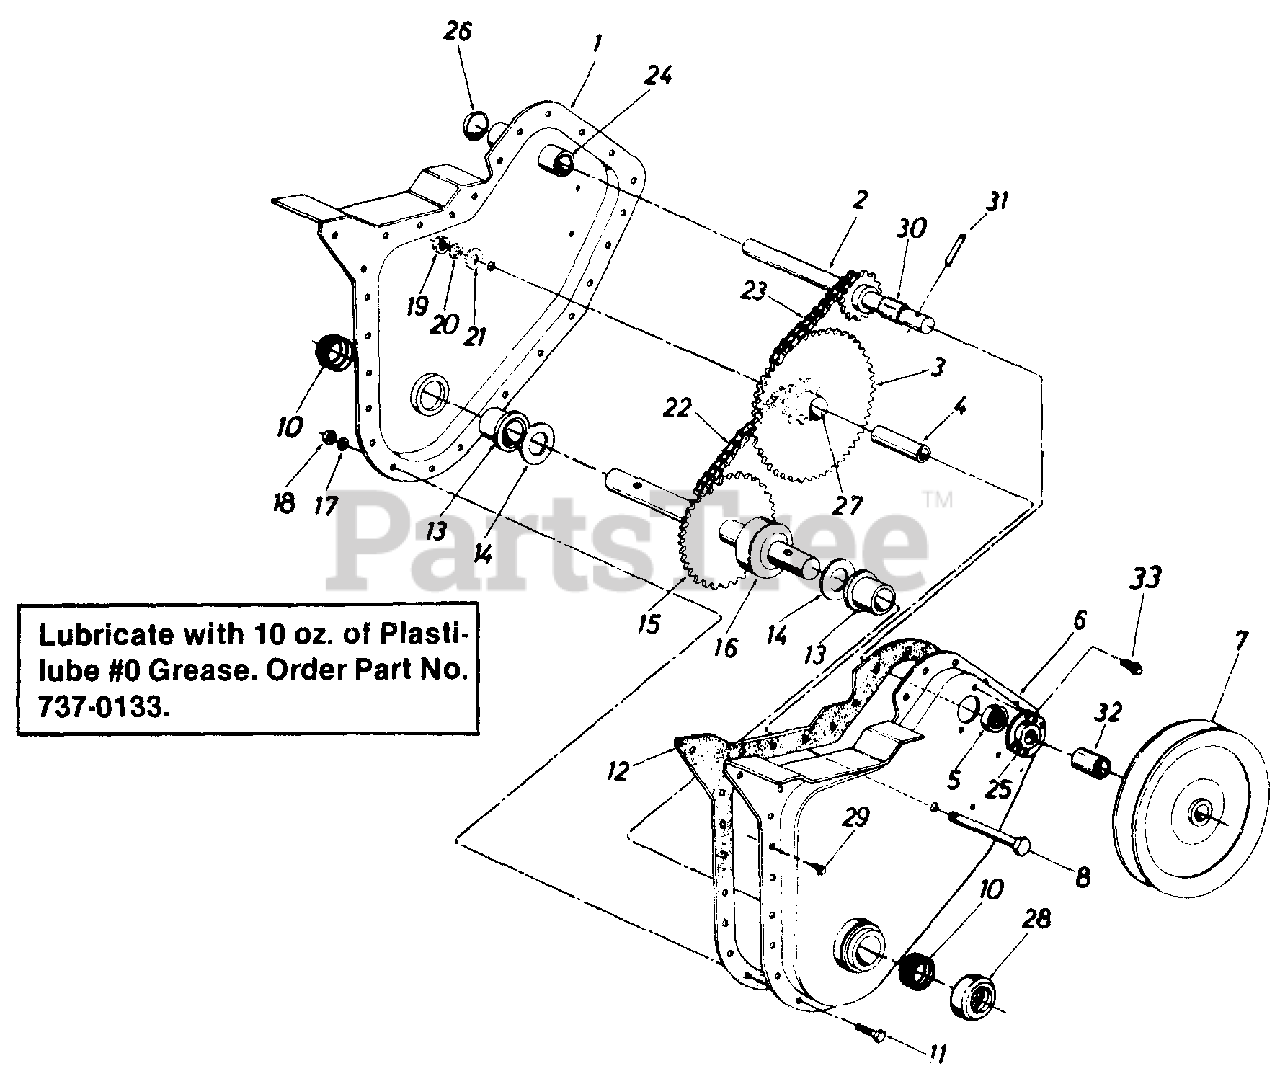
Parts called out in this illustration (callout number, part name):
1	Chain Case Ass'y. - R.H.
2	Input Shaft Ass'y.
3	Hub and Sprocket Ass'y.
4	Bearing Inner Race
5	Ball Bearing
6	Chain Case Ass'y. - L.H.
7	Pulley - Chain Case 5 1/2 x 1/2
8	Hex Bolt 3/8-24 x 2.50" Lg.
11	Hex Bolt 1/4-28 x .625" Lg.
12	Gasket
13	Flange Brg. .879 I.D.
14	Fl-Wash. .88 I.D. x 1.50 O.D. x .030
15	Tine Shaft Ass'y.
16	Spacer 7/8" I.D. x 2.0" O.D. x .68" Lg.
17	L-Wash. 1/4" Scr.
18	Hex Nut 1/4-28 Thd.
19	Hex Nut 3/8-24 Thd.
20	L-Wash. 3/8" Scr.
21	Bell-Wash. .406 I.D. x 1.130 O.D.
22	Chain #420 - .50" Pitch x 37 Links
23	Chain #35 - .375" Pitch x 49 Links
24	Bearing .62" I.D. x .813 O.D. x 1.31
25	Bearing Housing
26	Expansion Plug 13/16" Dia.
28	Dust Cap
29	Hex Wash. Hd. Self-Tap Scr. 1/4-20 x .50" Lg.
30	Spacer .63" I.D. x .77" O.D. x .38" Lg.
31	Spring Pin Spiral 1/4" Dia. x 1 1/2" Lg.
32	Spacer .647 x 1.25"
33	Hex Wash. Hd. Self-Tap Scr. 1/4-20 x .38" Lg.
